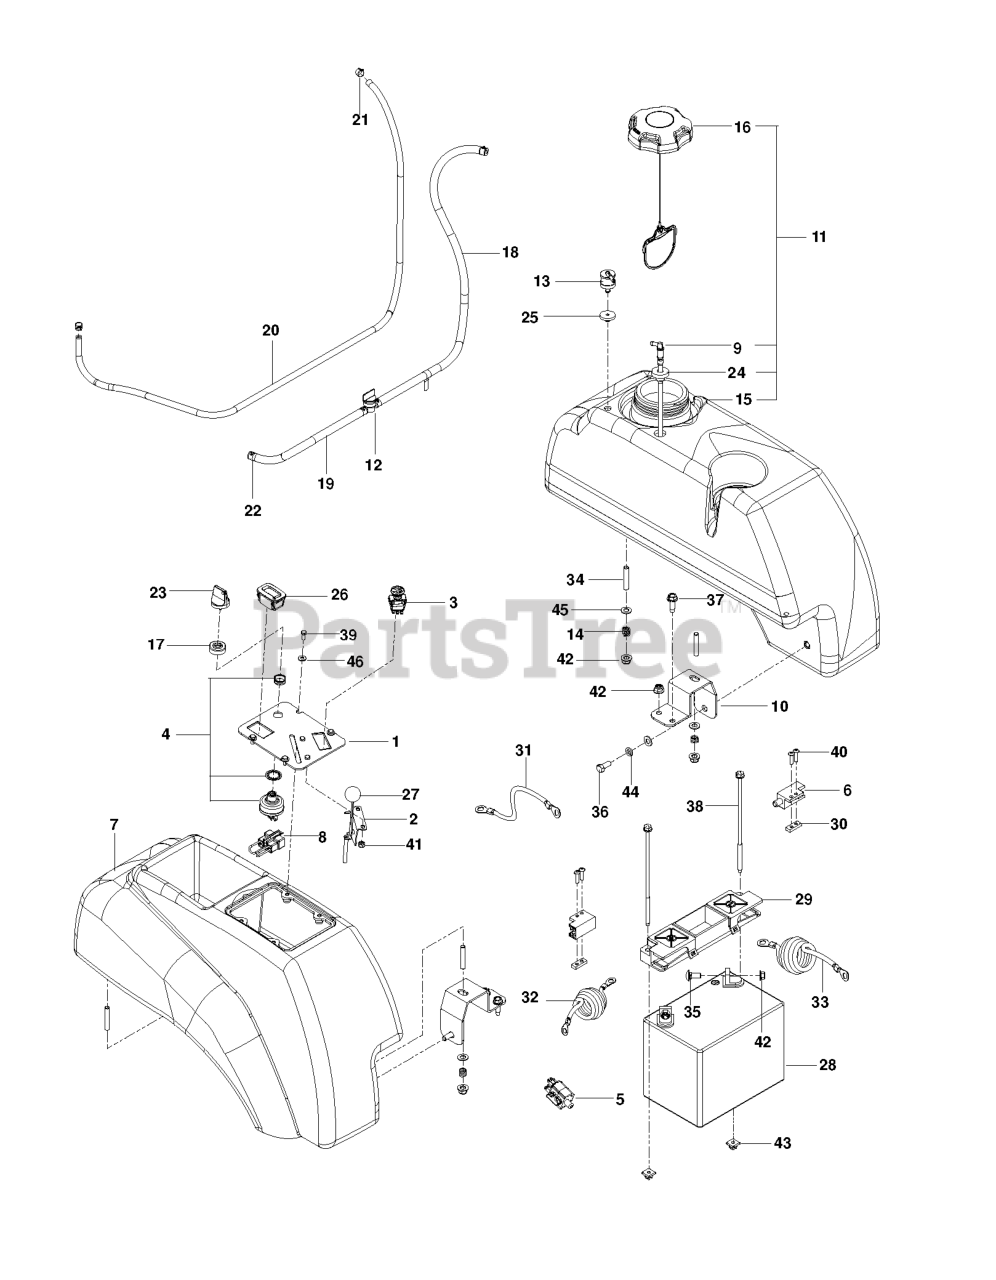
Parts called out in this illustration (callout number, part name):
1	RP.PLATE, CONSOLE, BLK
2	THROTTLE CABLE
3	SWITCH, PTO 10 AMP
4	SWITCH, IGNITION, INDAK
5	SWITCH, BRAKE 3P
6	SWITCH, INTERLOCK
7	FENDER CONSOLE
8	PLUG, TIMER
9	FITTING, FUEL
10	SUPPORT, TANK, BLK
11	ASSEMBLY, LT TANK, EPA GRAY
12	FUEL VALVE
13	VALVE.FUEL.CHECK
15	TANK, FUEL, LT-EPA
16	CAP, FUEL
17	CAP IGNITION NUT
18	HOSE, FUEL .25 ID X 26"
19	GAS LINE 10"
20	HOSE, VAPOR 3/16 X 48"
21	CLAMP, HOSE
22	HOSE CLAMP
23	KEY, IGNITION
24	RUBBER GROMMET
25	GROMMET, CHECK VALVE
26	RP.GUAGE.SRVCMNDR.HRMTR.
27	KNOB.ROUND.BALL.BLACK
28	BATTERY, 12 V 330 AMP
29	BATTERY HOLD DOWN
30	TAPPED PLATE
31	CABLE POSITIVE
32	POST.CABLE LONG
33	NEG. CABLE, 28"
34	STUD, 5/16C
35	BOLT 5/16C X 3/4" CARRIAGE
36	HCS 5/16C X 3/4
37	RP BLT 5/16-18 X 1 THRD FORM D
38	BOLT - 1/4-20 X 7.5
39	HCS #10-24 X 1/2
40	SCR #10-24 X .75 SKT HD BLK
41	NUT 10-24 NYLOC
42	5/16-18 NYLOC FLANGE NUT
43	PUSH NUT-NYLON
44	WASHER.LOCK.HVY.HLCL.SPR.5/16
45	FLAT WASHER 5/16 SAE
46	WASHER #10
